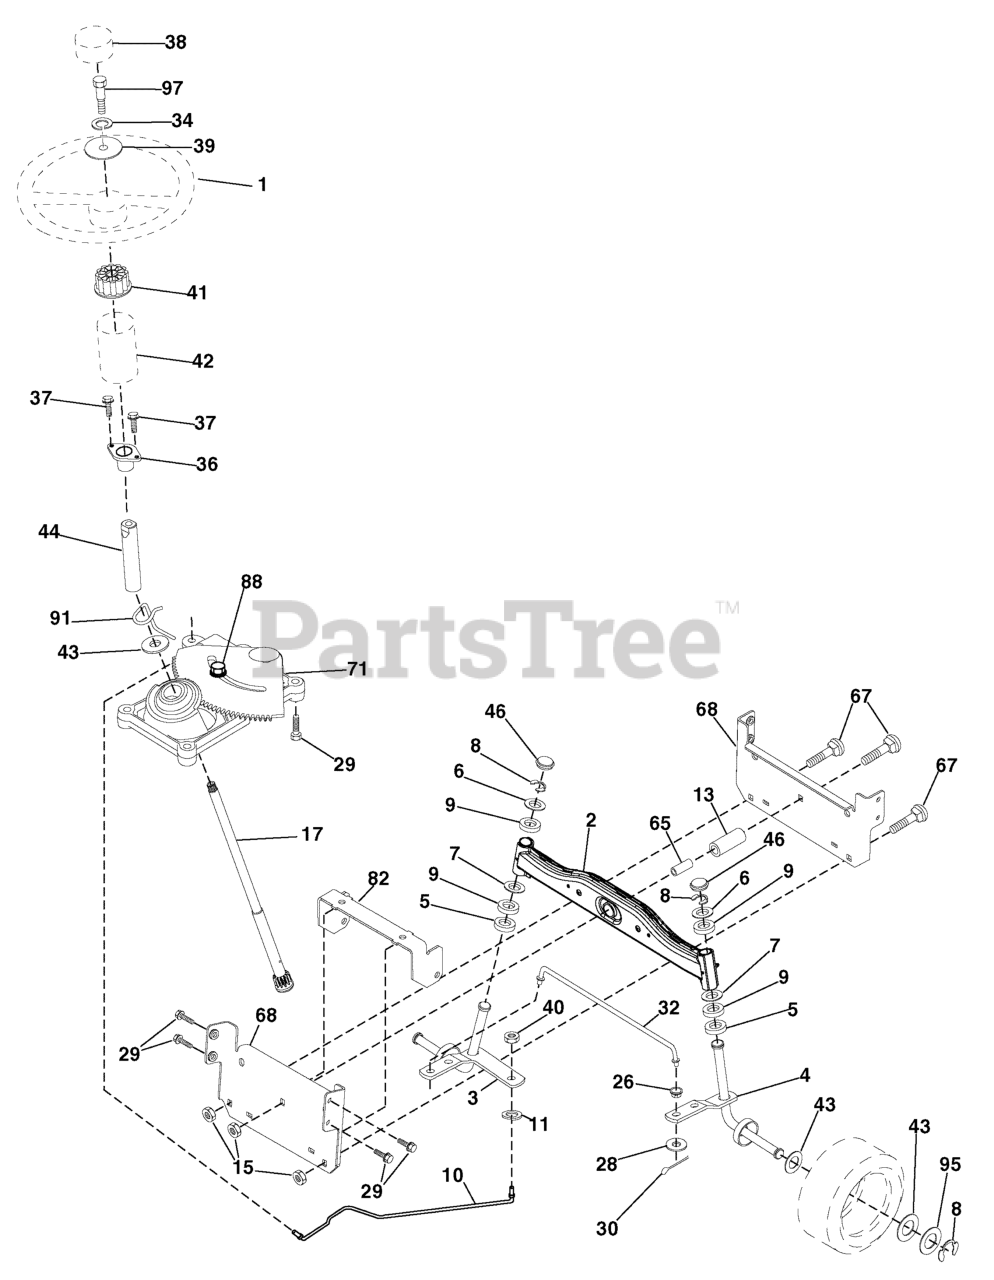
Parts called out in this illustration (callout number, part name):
1	Steering Wheel
2	Axle Assembly
3	Spindle Assembly, L.H.
4	Spindle Assembly, R.H.
5	Bearing, Race, Thrust, Hardened
6	Washer 25/32 x 1-5/8 x 16 Ga.
7	Washer 27/32 x 1-1/4 x 16 Ga.
8	Ring, Klip
9	Bearing Col. Strg.
10	Draglink
11	Washer, Lock
13	Spacer Brg Axle Front
15	Hexflange Lock
17	Shaft, Steering
26	Bushing, Link, Drag
28	Washer 13/32 x 7/8 x 16 Ga.
29	Screw 3/8-16 x 3/4
30	Pin, Cotter
32	Rod, Tie
34	Washer Lock Hvy Hlcl Spr. 5/16
36	Bushing, Steering
37	Screw
38	Insert, Steering Wheel
39	Washer 11/32 x 2-3/8 x 12 Ga.
40	Nut Crownlock 3/8-24
41	Adaptor, Steering Wheel
42	Boot, Steering Shaft
43	Washer 25/32 x 1-1/4 x 16 Ga.
44	Extension Shaft Steering
46	Cap, Spindle
65	Spacer Brace Axle
67	Bolt Rdhd Sqnk 3/8-16 x 2-1/4
68	Axle, Brace
71	Steering Asm
82	Bracket Susp Chassis Front
88	Bolt Shoulder 7/16-20
91	Clip Steering
95	Washer Hardened .793 x 1.637 x .060
97	Bolt Fin Hex 5/16-18 x 4
